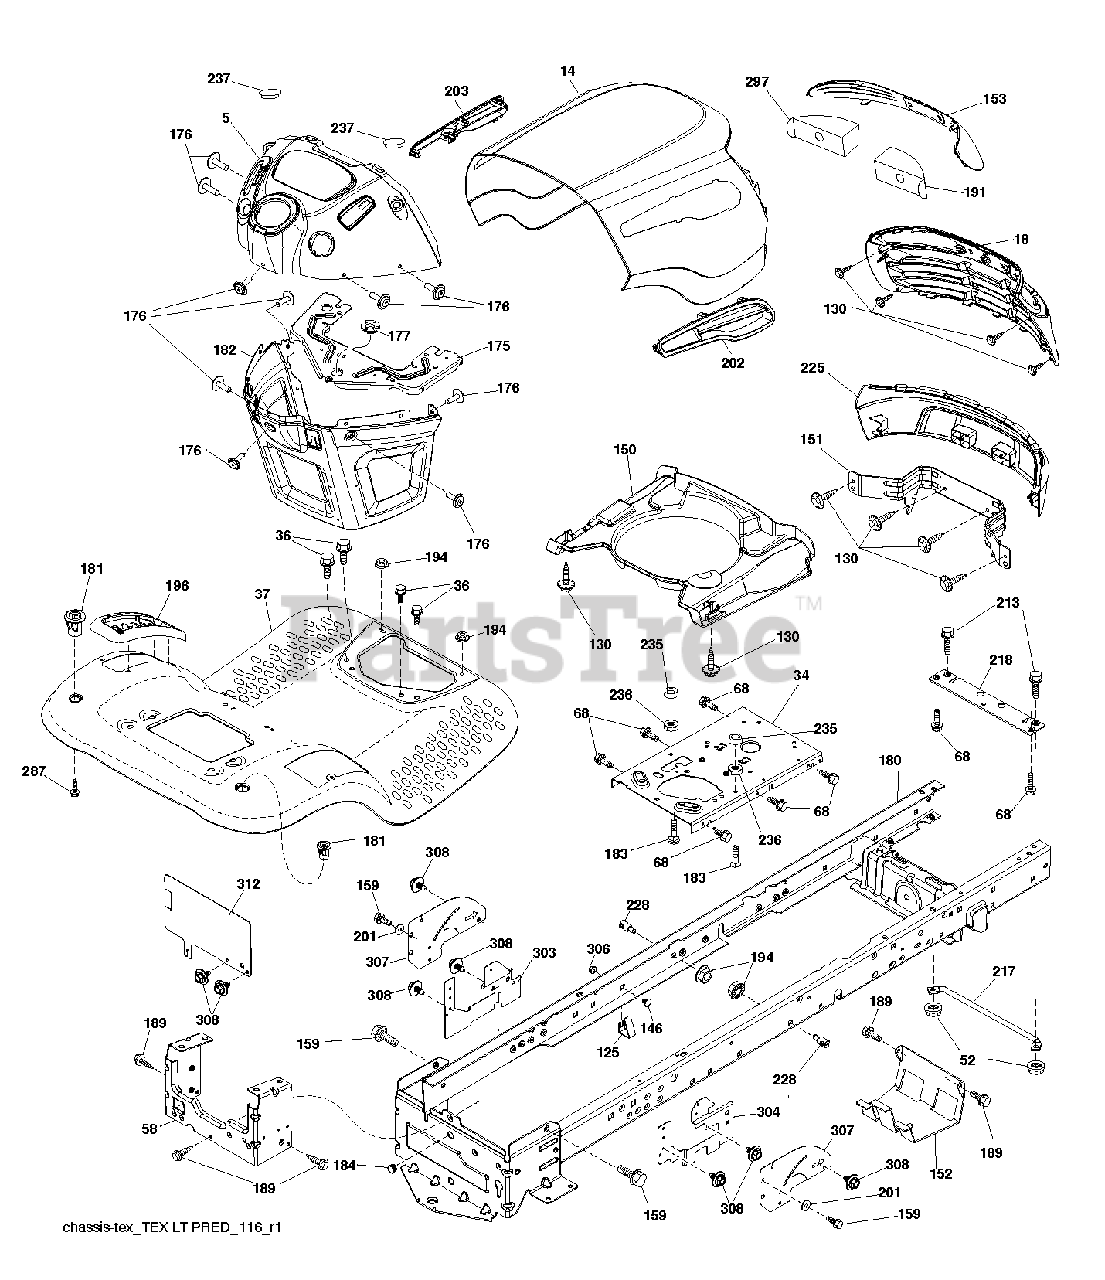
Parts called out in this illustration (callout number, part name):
36	SCREW 5/16"
52	LOCKNUT
58	DRAWBAR UPPER 2PC SMALL FENDER
125	Fuel Line Clip
130	SCREW.#10 X 0.750.BOS THREAD
146	BOLT.RDHD.SHT.SQNK.3
151	BRACKET.PIVOT.ALPHA.LT
152	SHIELD BROWNING
159	SCREW, 3/8-16X3/4
175	CROSSMEMBER
176	SCREW.#10-24X5/8.RN.QU
177	BUSHING STEERING
180	CHASS.WLDMNT.TL.12GA/2P.48/54
181	FEND/FTRST.PCH.CPH.NFW
182	DASH.LWER.PREDATOR/HUSQ.LT
183	BOLT.5/16-18X1-1/4 FULL THD
184	PLUG.DEMO.625
189	SCREW
191	INSERT.REFLECT.PREDATOR.LT.RH
194	NUT LOCK HEX FLANGE 5/16-18
196	CONSOLE.ASM.DECKLFT.BL/RBT.TLT
201	WASHER
213	BOLT
217	ROD.PIVOT.HOOD
218	X-PIECE.HOOD.STOP.NON/
228	STUD.FASTNER.W/ANTI-ROTATE
235	SPACER FENDER
236	NUT.CENTERLOCK.5/16-
237	PLUG.MOUNT.CARGO.BLK
297	REFLECTOR.INSERT.PRED.LH.LT
304	SHIELD.LWR.RH.LT30DECK.PNT.BLK
306	NUT LOCK FLG 3/8-16 UNC
308	BOLT, 5/16-18 X 1 3/4
